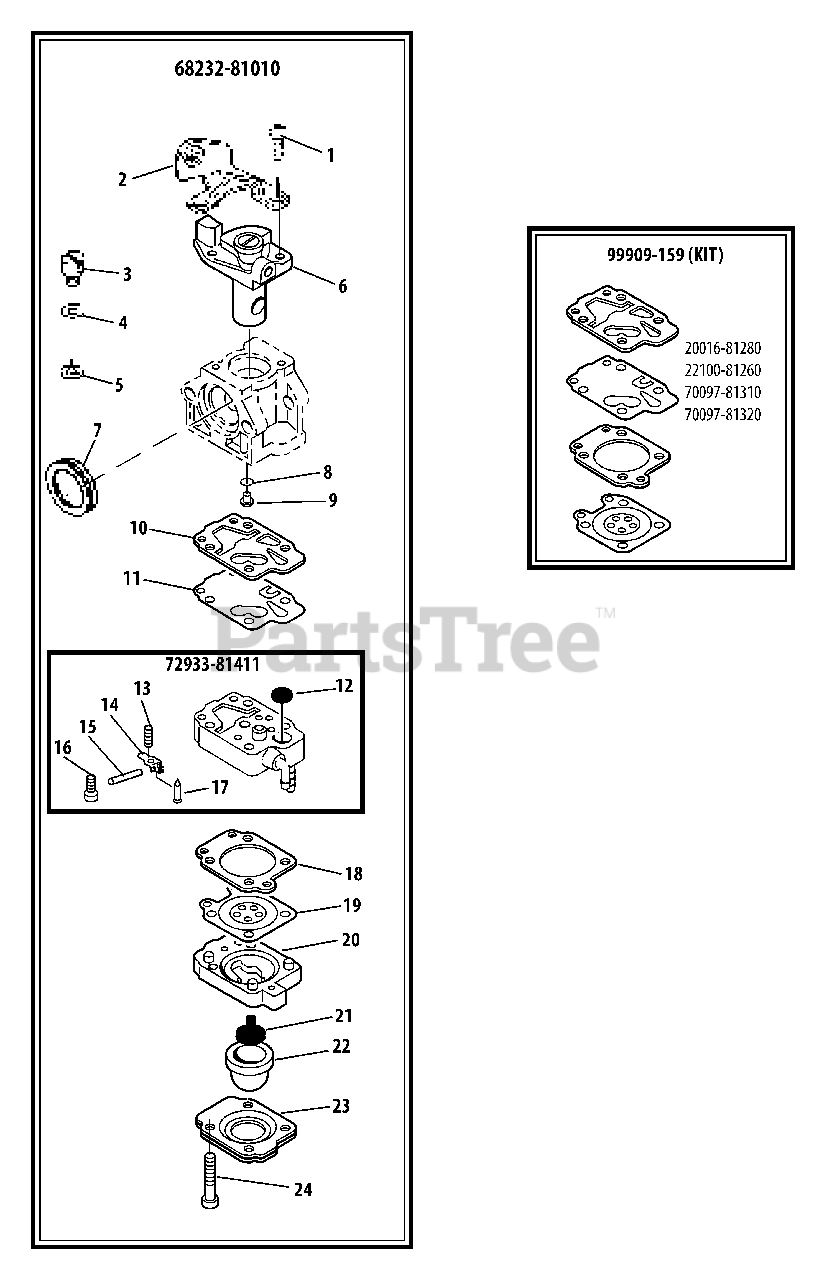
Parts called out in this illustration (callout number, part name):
1	SCREW
2	BRACKET, THROTTLE CABLE
3	SWIVEL
4	WASHER
5	E-RING
6	THROTTLE VALVE ASSY
7	RING, PACKING
8	O-RING
9	MAIN JET (#48)
10	GASKET, PUMP
11	DIAPHRAGM, PUMP
12	SCREEN, FUEL INLET
13	SPRING, METERING LEVER
14	LEVER, METERING
15	PIN, METERING LEVER
16	SCREW
17	VALVE, INLET NEEDLE
18	GASKET, METERING DIAPHRAGM
19	DIAPHRAGM, METERING
20	BODY ASSY, PURGE
21	VALVE, CHECK
22	BULB, PURGE
23	RETAINER, PURGE BULB
24	SCREW
68232-81010	CARBURETOR
72933-81411	BODY ASSY, PUMP
99909-159	GASKET / DIAPHRAGM KIT
